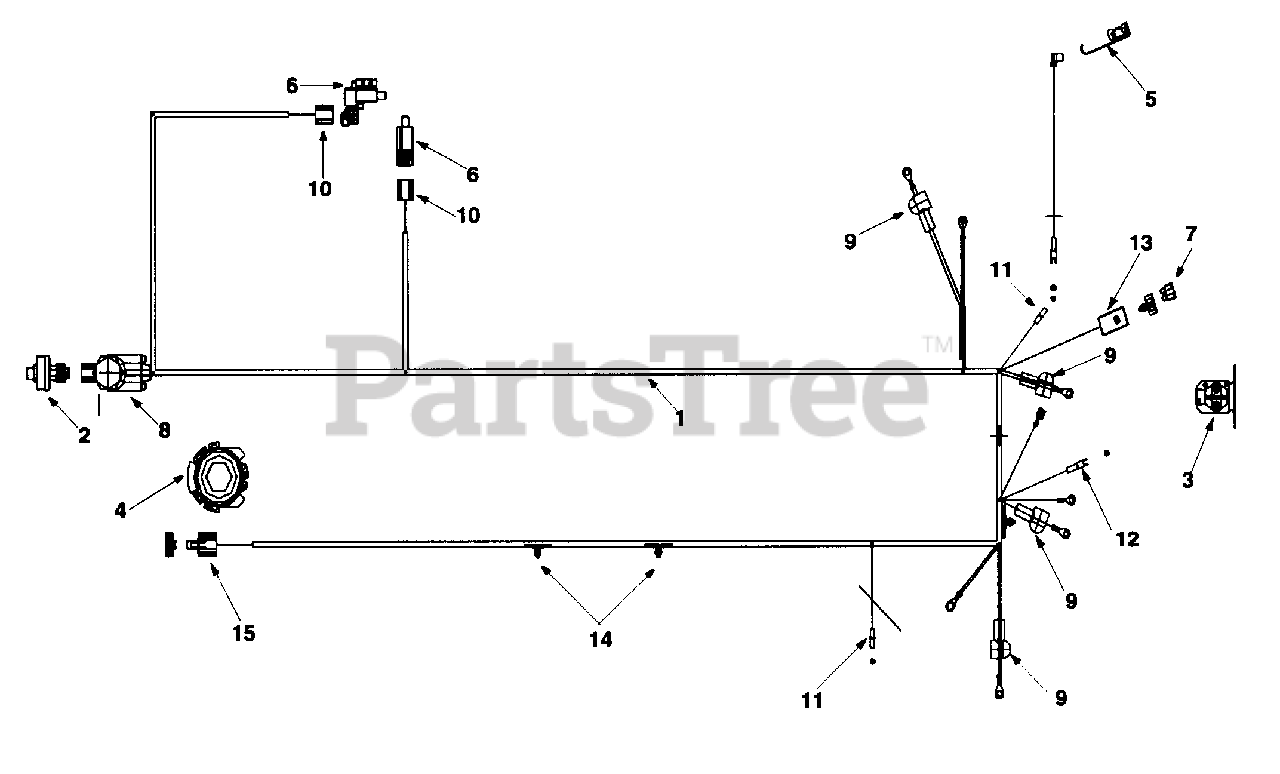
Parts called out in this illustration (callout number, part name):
1	Harness Assembly w/o relays
2	Ignition Switch: 5 Pin
3	Solenoid: 12 V. 100 amp.
4	Seat Switch
5	Spring Switch
6	Interlock Switch
7	Fuse: 20 amp.
8	Battery Cover
9	Battery Cover: Red
10	Connecter
11	Connecter
12	Connecter
13	Fuse Holder w/Clip
14	Harness Clip
15	Connecter
